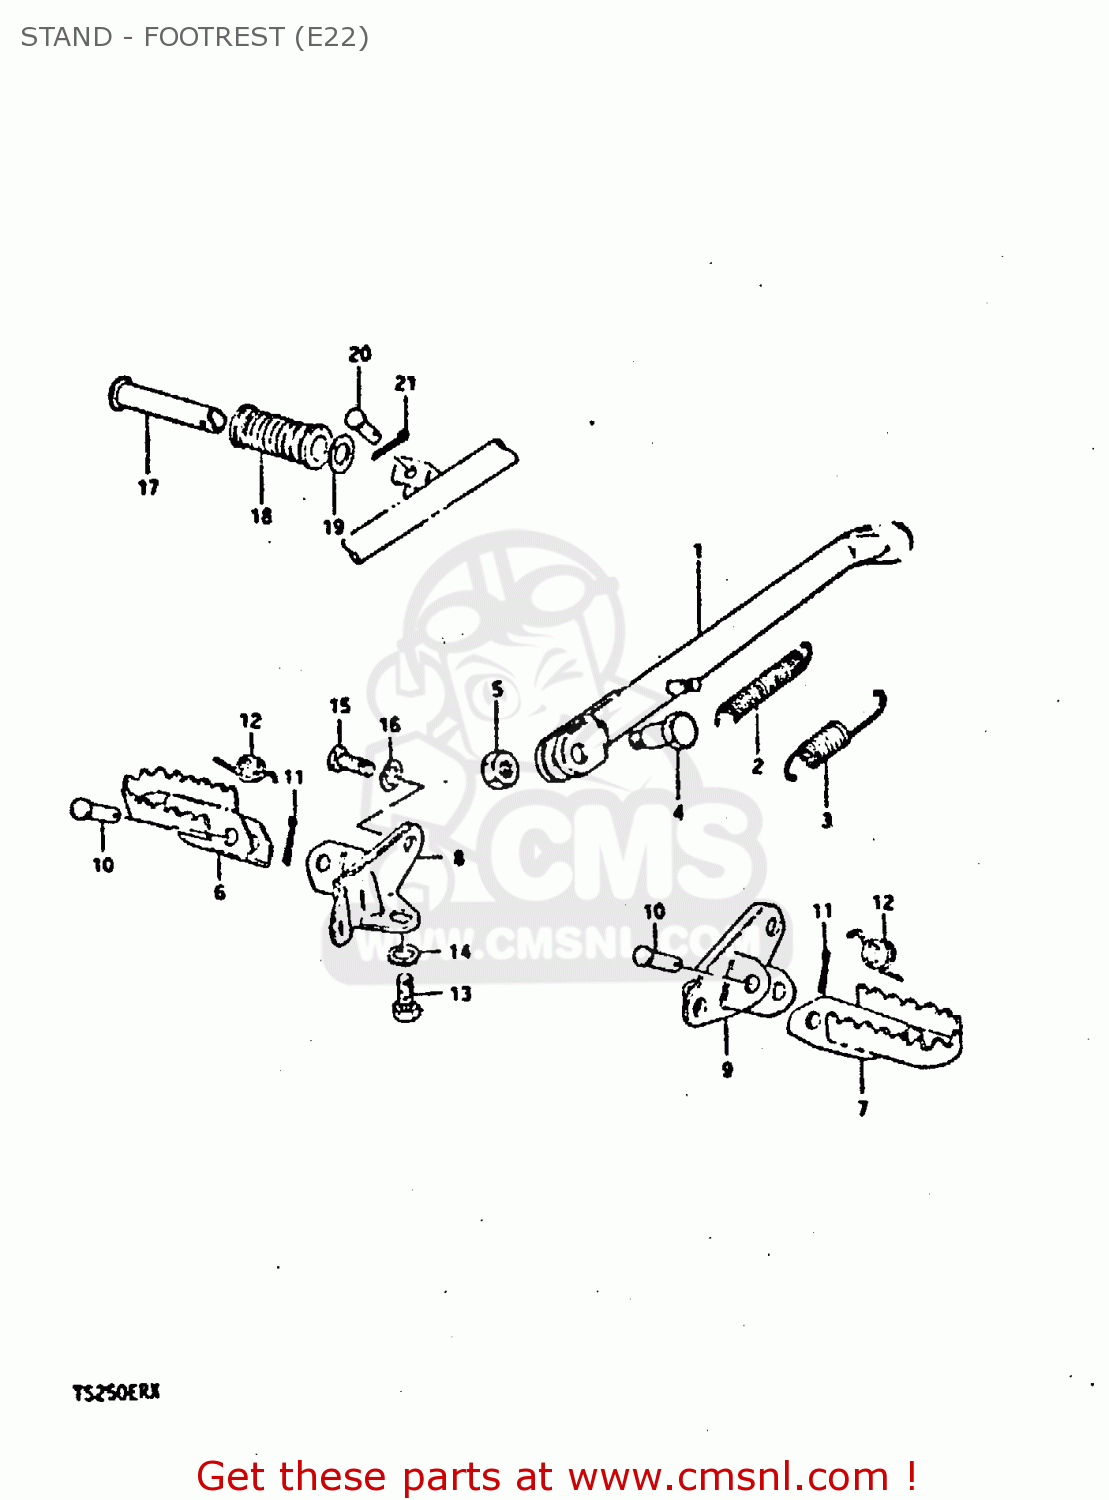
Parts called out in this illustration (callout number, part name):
1	STAND, PROP
2	SPRING
3	SPRING, OUTER
4	BOLT
5	NUT
6	HOLDER,FRONT FOOTREST,RIGHT
7	HOLDER,FRONT FOOTREST
8	FOOTREST,FRONT
9	FOOTREST
10	PIN
11	PIN 20X20
12	SPRING
13	BOLT
14	LOCK WASHER
15	BOLT 8X16
16	WASHER,LOCK,8.
17	BAR,FOOTREST RUBBER
18	RUBBER,PILLION FOOTREST
19	WASHER (19.5X32X2)
20	PIN
21	PIN 20X20
